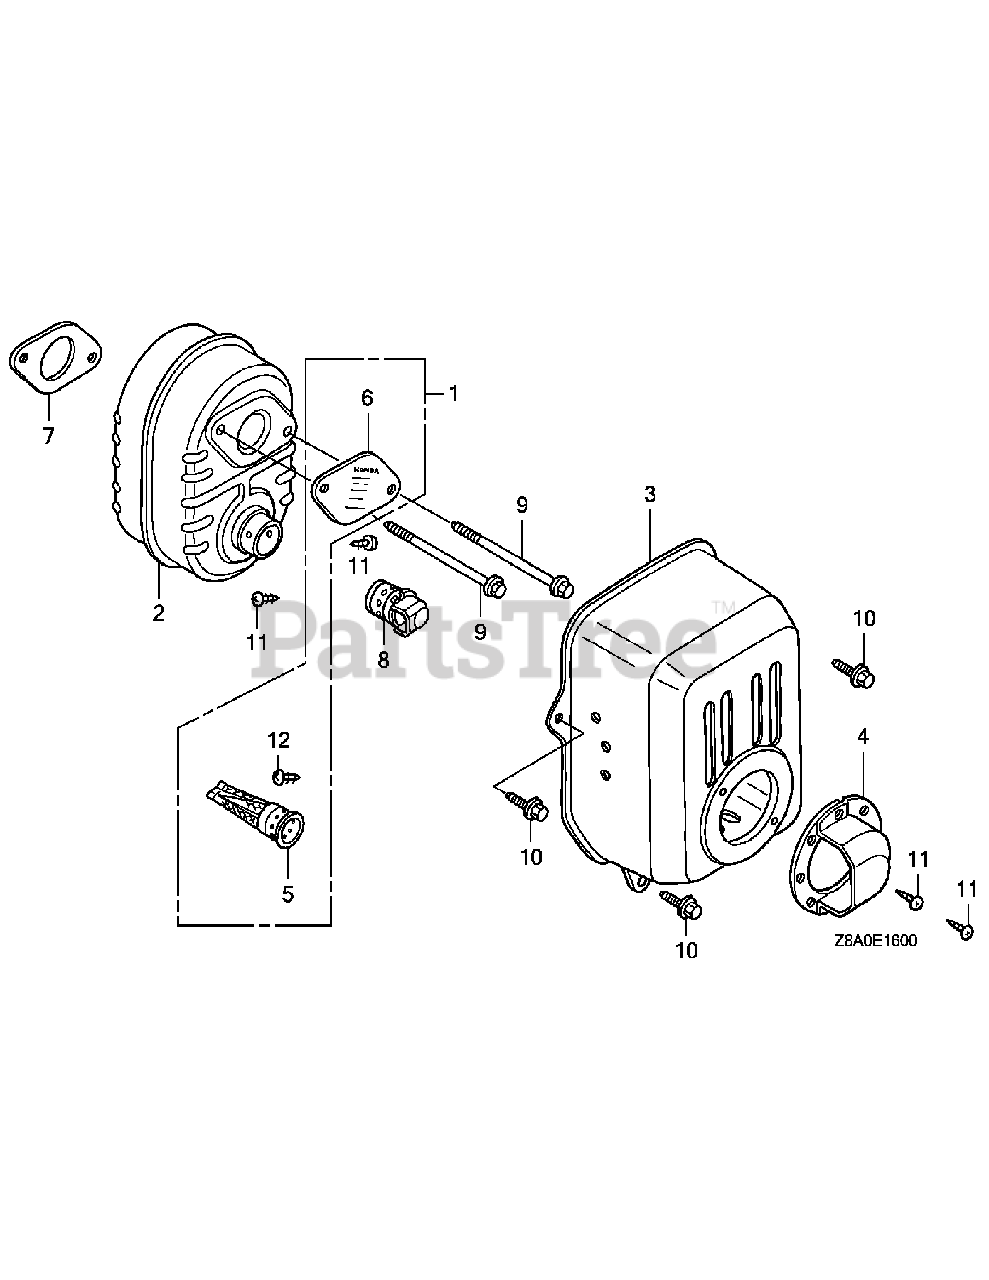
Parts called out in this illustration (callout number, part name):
1	Arrestor Kit, Spark
2	Muffler Complete
3	Protector, Muffler
5	Arrestor Complete, Spark
6	Plate, Arrestor Number
7	Gasket, Muffler
9	Bolt, Flange 6 x 79 (CT200)
10	Bolt, Flange 6 x 12 (CT200)
12	Screw, Tapping 4 x 6
